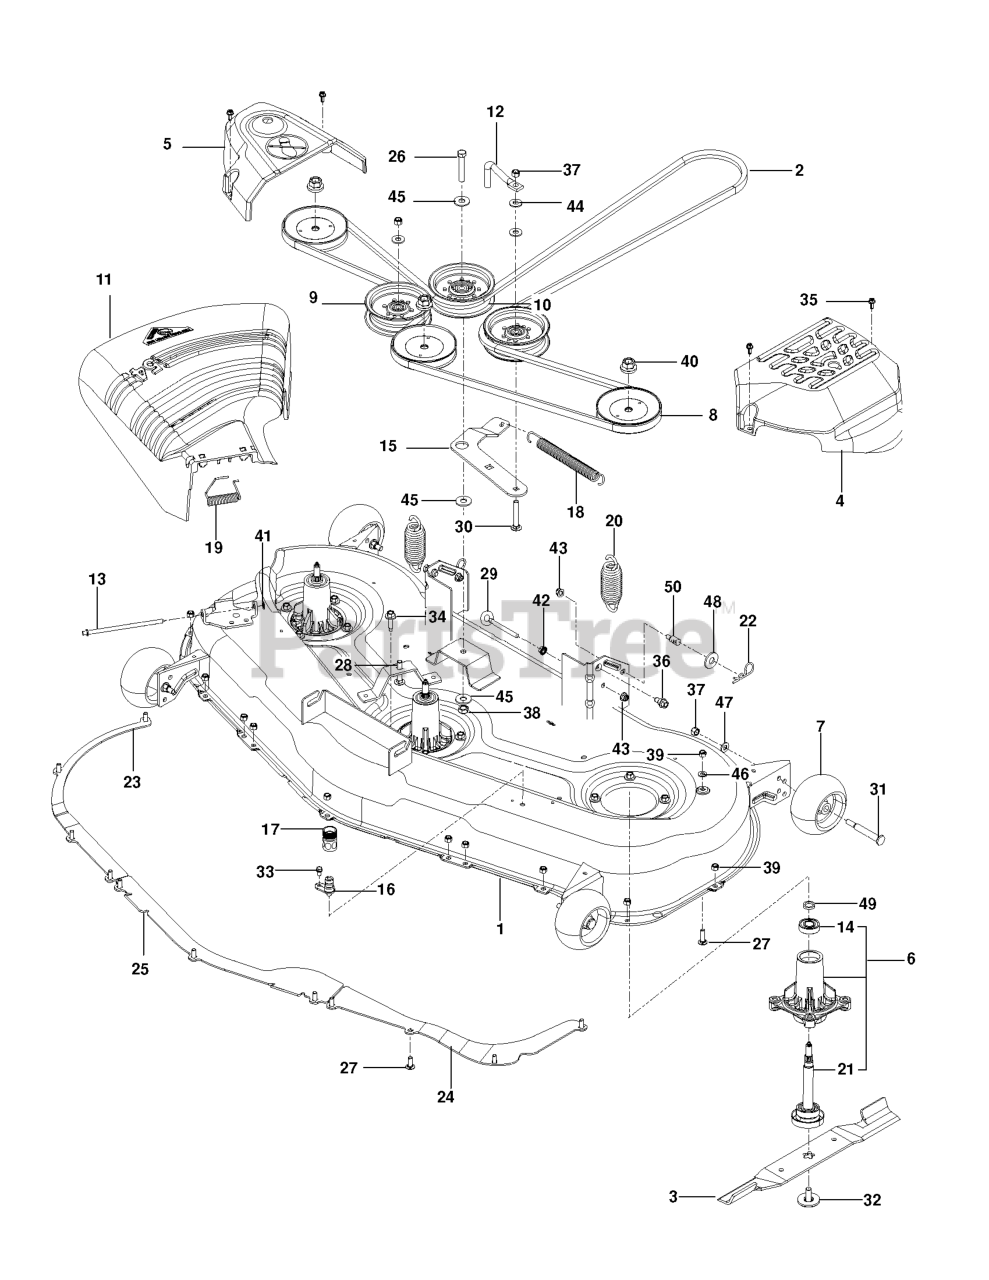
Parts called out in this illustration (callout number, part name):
1	DECK SVC W/DECALS 54" ORG
2	BELT.DECK.52".54"
3	BLADE.BAGGING.54"
4	COVER.MANDREL.LH.DECK.54"
5	COVER.MANDREL.RH.DECK.54"
6	MANDREL GREASABLE
7	GAUGE WHEEL
8	PULLEY
9	PULLEY.IDLER.2006
10	PULLEY.IDLER.MWR.STATI.LH
11	DEFLECTOR, 54"
12	BELT KEEPER 5"
13	ROD, HINGE
14	BEARING, BALL
15	ARM.IDLER.BLACK
16	PORT.WASHOUT
17	COUPLING.QUICK CONNECT
18	SPRING, DECK BELT
19	TORSION SPRING
20	SPRING
21	SHAFT ASM MANDREL
22	HAIRPIN #4
23	BAFFLE, RIGHT 54"
24	BAFFLE LEFT 54
25	BAFFLE, CENTER, 54"
26	BOLT 7/16-14 X 2-1/2 GR 5 ZD
27	BOLT 5/16C X 3/4" CARRIAGE
28	RHSNB 3/8C X 2
29	EYE BOLT 5/16 X 3.50
30	CARRIAGE BOLT 3/8-16 X
31	SHOULDER BOLT 1/2X2-5/8 ZD SPE
32	BLADE BOLT ASSY-7/16" TB REPL
33	BOLT 1/4-20 X 1/2 HWST
34	WASHER HEAD SCREW
35	SCREW- 1/4-20 X 5/8
36	BOLT.SHOULDER
37	NUT 3/8-16 NYLOC
38	7/16-14 HEX NUT W/NYL RING ZD
39	NUT 5/16 NYLOC
40	LOCKNUT - 9/16
41	PUSH NUT
42	NUT 5/16C WHIZ
43	5/16-18 NYLOC FLANGE NUT
44	WASHER 3/8 FLAT
45	WASHER 7/16 FLAT ZD
46	FLAT WASHER 5/16 SAE
47	WASHER 3/8 SAE FLAT
48	WASH USS FLAT 1/2
49	WASHER.SPACER.MANDREL
50	STUD.FASTNER.W/ANTI-ROTATE
